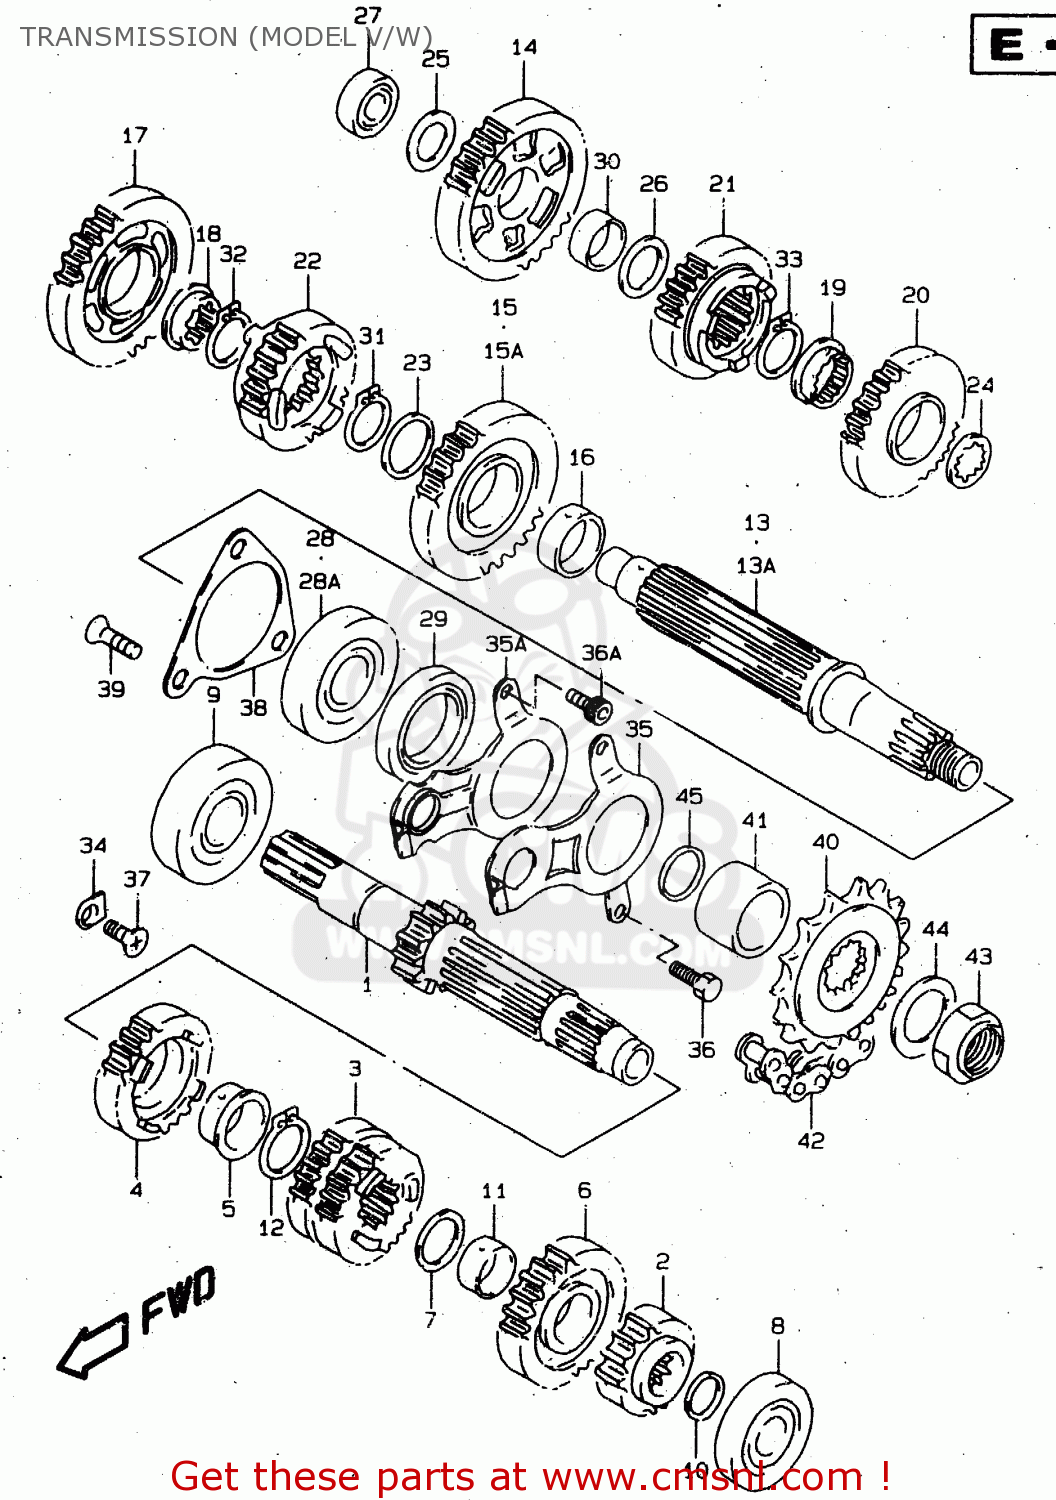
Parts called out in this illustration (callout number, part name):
1	SHAFT,COUNTER (NT:12)
2	GEAR,2ND DRIVE(NT:15)
3	GEAR,THIRD & FOURTH DRIVE,N
4	GEAR,FIFTH DRIVE (NT:23)
5	BUSHING,FIFTH DRIVE GEAR
6	GEAR,SIXTH DRIVE (NT:24)
7	SHIM(22X30X1)
8	BEARING 20X47X14
9	BEARING(25X62X17)
10	O RING(D:1.9,ID:16.6)
11	BUSHING
12	CIRCLIP
13	SHAFT,DRIVE
13A	SHAFT,DRIVE
14	GEAR,1ST DRIVEN(NT:32)
15	GEAR,SECOND DRIVEN (NT:29)
15A	GEAR,SECOND DRIVEN (NT:29)
16	BUSH,2ND DRIVEN GEAR
17	GEAR,THIRD DRIVEN (NT:27)
18	BUSH
19	BUSH
20	GEAR,FOURTH DRIVEN (NT:27)
21	GEAR,FIFTH DRIVEN (NT:25)
22	GEAR,SIXTH DRIVEN (NT:24)
23	WASHER(27X36X1)
24	WASHER,LOCK
25	SHIM(20X34X1)
26	SHIM(22X34X1)
27	BEARING(20X52X15)
28	BEARING(28X68X18)
28A	BEARING(28X68X20)
29	SEAL,OIL(38X52X8)
30	BUSH
31	CIRCLIP
32	CIRCLIP
33	CIRCLIP
34	RETAINER
35	RETAINER,DRIVE SHAFT OIL SEAL
35A	RETAINER,DRIVESHAFT O
36	BOLT
36A	BOLT,STRANGER
37	SCREW
38	RETAINER,DRIVE SHAFT BEARING
39	SCREW(6X12)
40	SPROCKET,ENGINE (NT:17)
41	SPACER,ENGINE SPROCKET
42	CHAIN ASSEMBLY RK50GSVZ1.1
43	NUT
44	SHIM(25X40X1.5)
45	O RING(D:2.4,ID:23.7)
